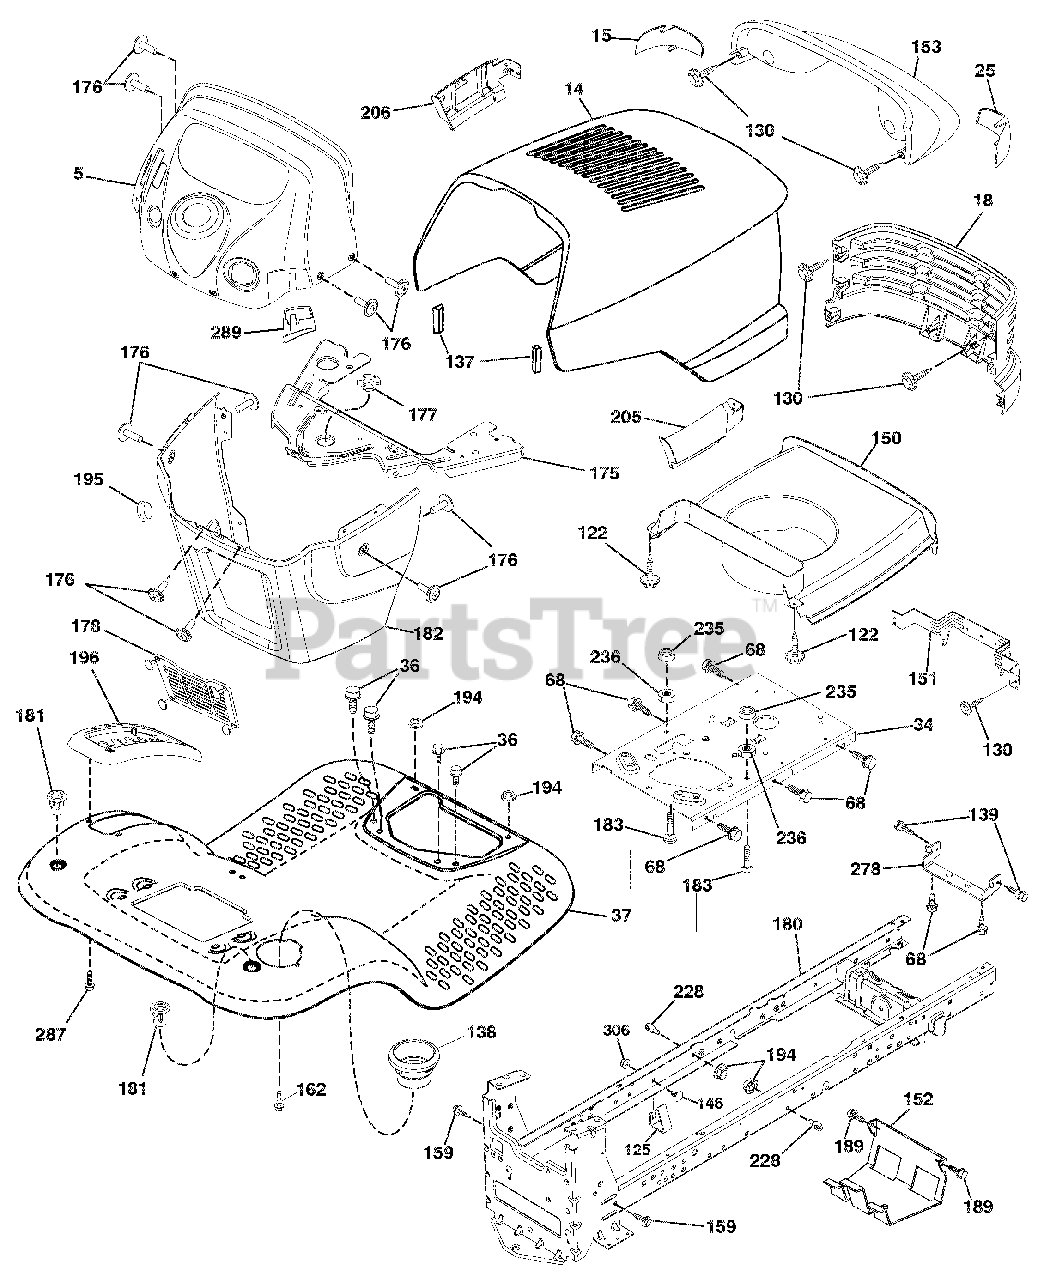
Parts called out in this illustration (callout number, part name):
5	DASH STEALTH ELE RECT 428 TEX
15	LENS ELITE ARIENS BLACK
18	GRILLE ELITE ARIENS BLACK
25	LENS ELITE HUSQ CLEAR RH
34	PLATE.ENGINE.WELDED.CHASSIS
36	SCREW.5/16-18X3/4.SMGML.TAP/R
37	FENDER TLT W/CPH W/FW 422
68	SCREW.THDROL.5/16-18 X 1/2TYTT
122	SCREW TO 32 X 5/8
125	CLIP.FUEL.LINE
137	BUMPER HOOD LARGE 1.75
138	CUPHOLDER TL TEX 428
139	BOLT SHOULDER 5/16-18
150	AIR DUCT ENGINE ELITE SV
151	BRACKET PIVOT LASR/ELTE/HUSQLT
152	SHIELD.BROWNING.W/TEX
153	ASM LIGHT BOX
159	SCREW.HEXWSH THDR3/8-16X3/4.BL
162	SCREW.HEX.WSH.HI-LO.1/4X1/2UNC
175	CROSSMEMBER LT
176	SCREW.#10-24X5/8.RND.QUDRX.GIM
177	BUSHING.STEERING.YT/GT
178	CARGO ASM NET
180	CHASS WLDMT TL 12 GA/2PC 18/22
181	BUSHING MNT FEND CRGO BLK TEX
182	DASH TOWER LT CCS
183	BOLT.FIN.HEX.5/16-18 UNC X1-1/
189	SCREW.5/16-18X3/4.SMGML.TAP/BL
194	Nut, Lock Hex Flange 5/16-18 u
195	PLUG HOLE DASH TOWER
196	CONSOLE ASM.DECKLFT.BL/RBT.TLT
205	SKIRT SIDE RH ELITE HUSQ 428
206	SKIRT SIDE LH ELITE 428
228	STUD.FASTNER.W/'D'ANTI-ROTATIO
235	SPACER.FENDER
236	NUT.CENTER LOCK.5/16-18 UNC
278	X-PIECE HOOD
287	SCREW.HEX.WASHEAD.1/4-20 X 3/8
289	PLUG CRUISE CONTORL
306	Nut, Hex, Flangelock 3/8-16
